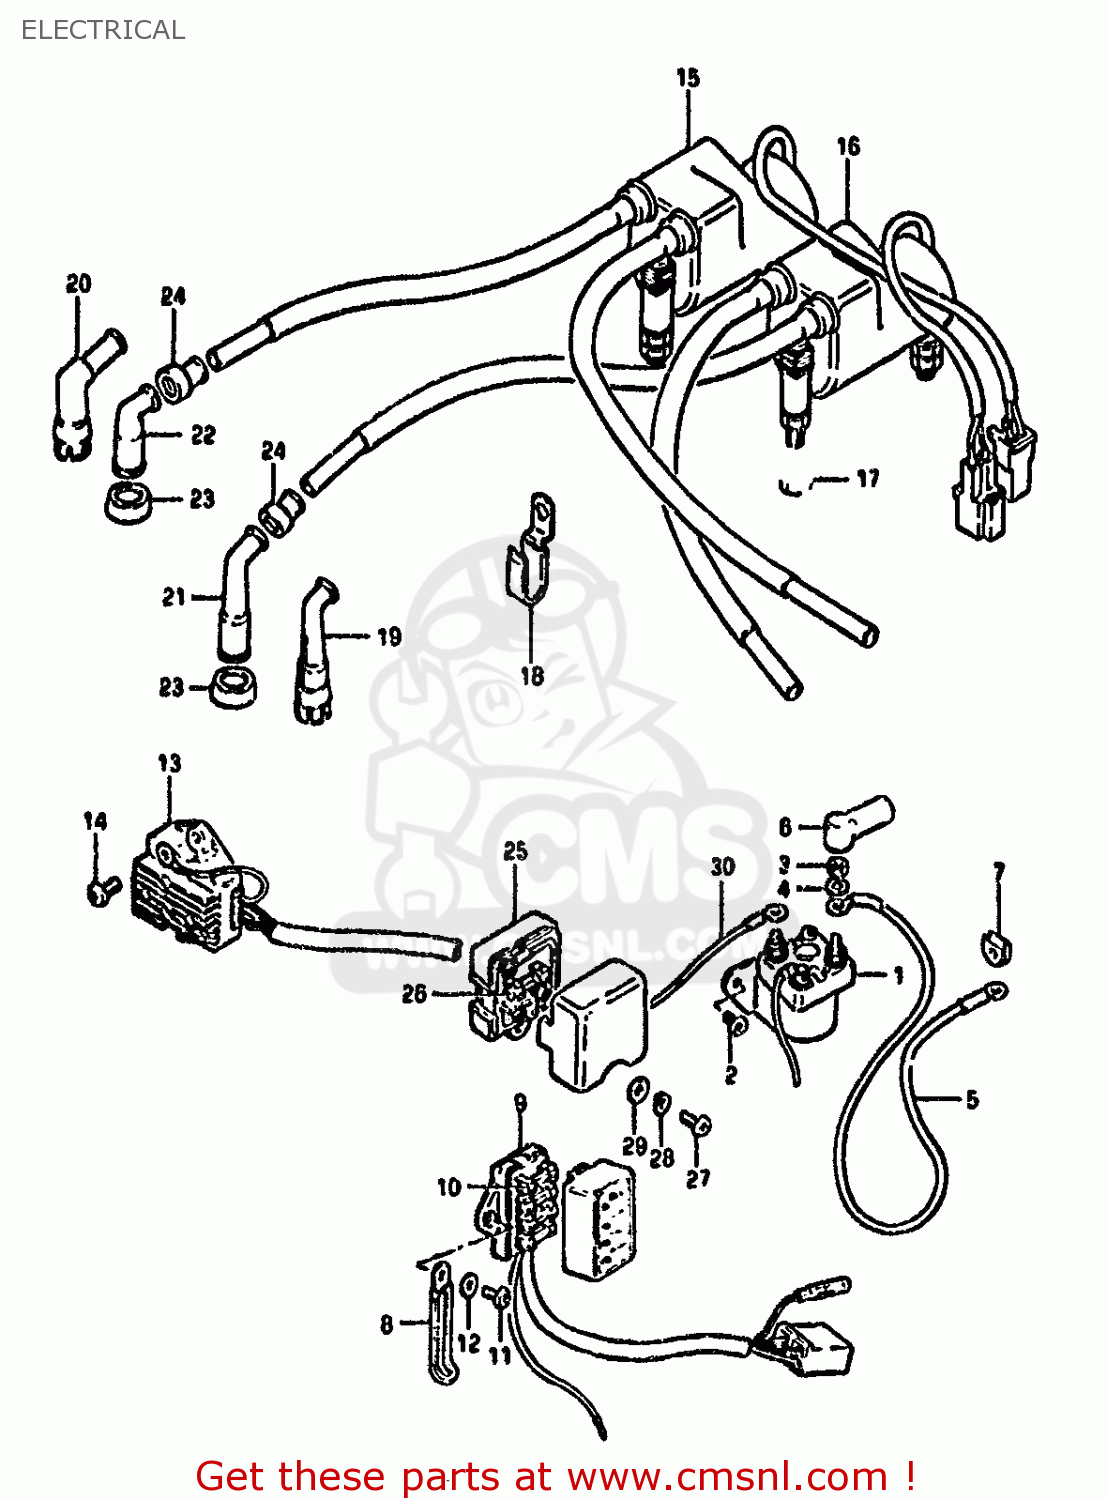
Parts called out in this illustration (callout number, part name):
1	RELAY ASSY,STARTING MOTOR
2	SCREW
3	NUT 6MM
4	LOCK WASHER
5	WIRE,STARTER MOTOR LEAD
6	CAP,STARTER RELAY
7	GROMMET,STARTER CABLE
8	CLAMP
9	BOX ASSEMBLY,FUSE
10	FUSE(15A)
11	SCREW 6X12
12	WASHER
13	RECTIFIER ASSEMBLY
14	SCREW
15	COIL ASSEMBLY,IGNITION
16	COIL ASSEMBLY,IGNITION
17	NUT
18	CLAMP
19	CAP,SPARK PLUG
20	CAP, SPARK PLUG (S)
21	CAP ASSY,SPARK PLUG
22	CAP,SPARK PLUG
23	SEAL,SPARK PLUG
24	SEAL,SPARK PLU
25	TERMINAL ASSEMBLY,POWER SO
26	FUSE(10A)
27	SCREW
28	LOCK WASHER
29	WASHER
30	WIRE
